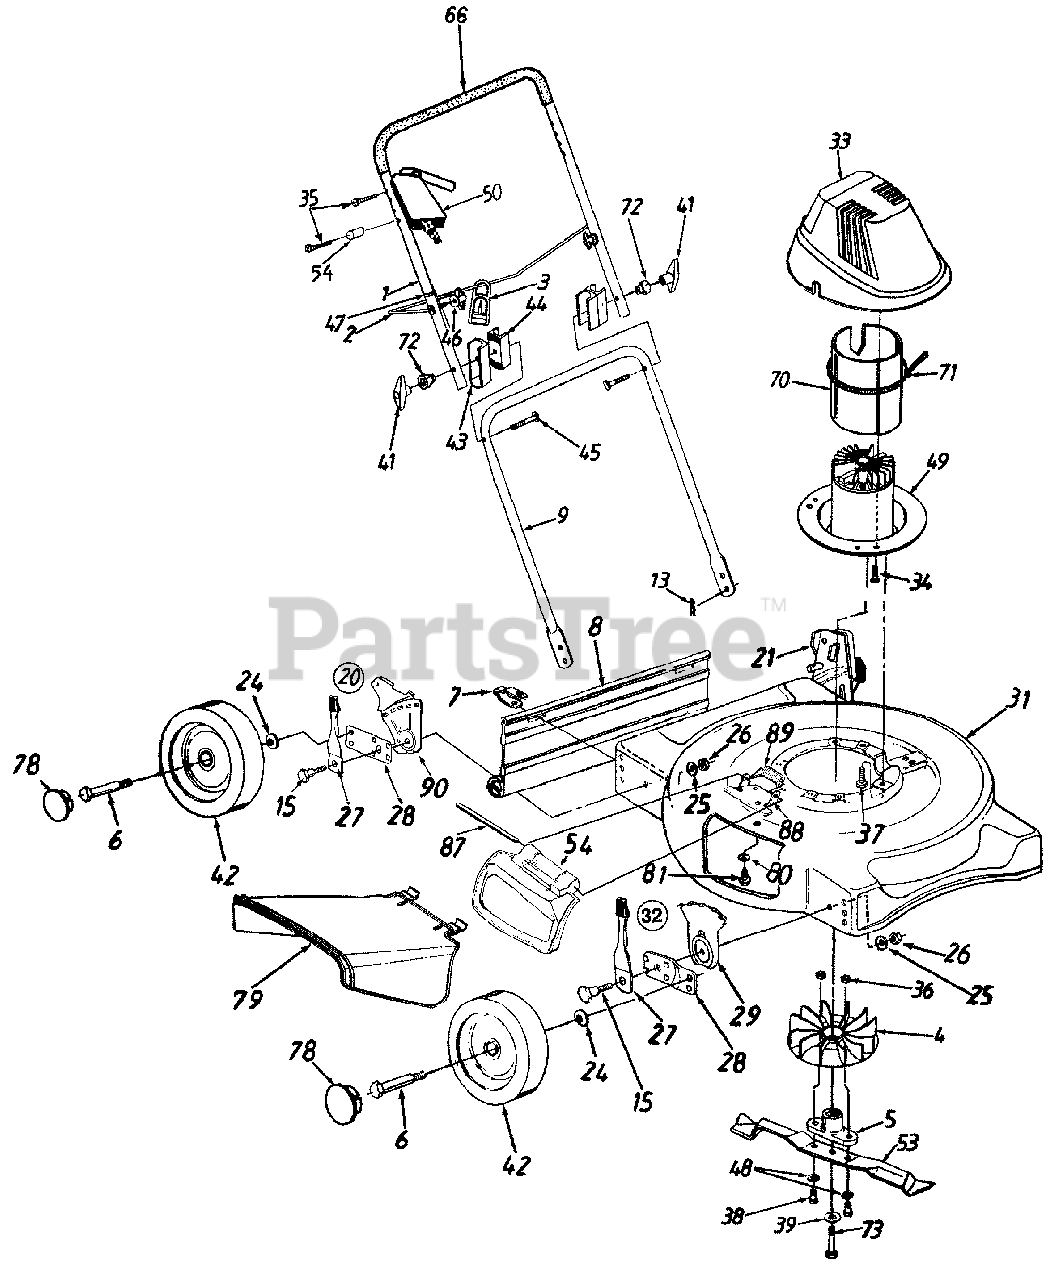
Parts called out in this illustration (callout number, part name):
3	Strain Relief Cord
5	Blade Adapter
6	Axle Bolt
7	Hinge Clip
8	Rear Flap
15	Shld. Bolt .5" Dia. x .434"
24	Spr. Washer .401 x .870 x .063
25	Bell Washer .39" I.D. x 1.38" O.D.
26	Hex Nut 3/8-16 Thd.
27	Spring Lever Assy. w/Knob
29	Height Adj. Plate
33	Motor Cover
34	Screw #10-24 x .75" Lg.
35	Oval C-Sunk Screw 1/4-20 x 1.81
36	Lock Nut 3/8-24 Thd.
37	Hex Lock Wash. TT-Tap Scr. 3/8-16 x 1.00"
38	Hx Hd.3/8-24: 1.25 Lg.
39	Bell Washer .396" I.D. x 1.14"
41	Plastic Knob
42	Wheel Assy. Comp. (8" x 1.75")
43	Upper Handle Insulator
44	Lower Handle Insulator
45	Carriage Bolt 5/16-18 x 3" Lg.
46	Wing Nut 1/4-20 Thd.
47	Cable Tie
48	Bell Wash. .39 x 1.13 x .062
49	Motor, Cord & Switch Assy.
50	Switch Assembly.
53	18" Blade
54	Mulching Plug
66	Foam Grip
70	Insulator
71	Cable Tie
72	Insulator Knob
73	Hex Bolt 3/8-24 x 2.5" Lg.
78	Hub Cap
78	Chute Deflector
80	Bell-Wash. 1/4" I.D.
81	Hex Wash. Hd. TT-Tap Scr. 1/4-20 x .5" Lg.
87	Hinge Pin
89	Torsion Spring
90	Handle Bracket Ass'y
